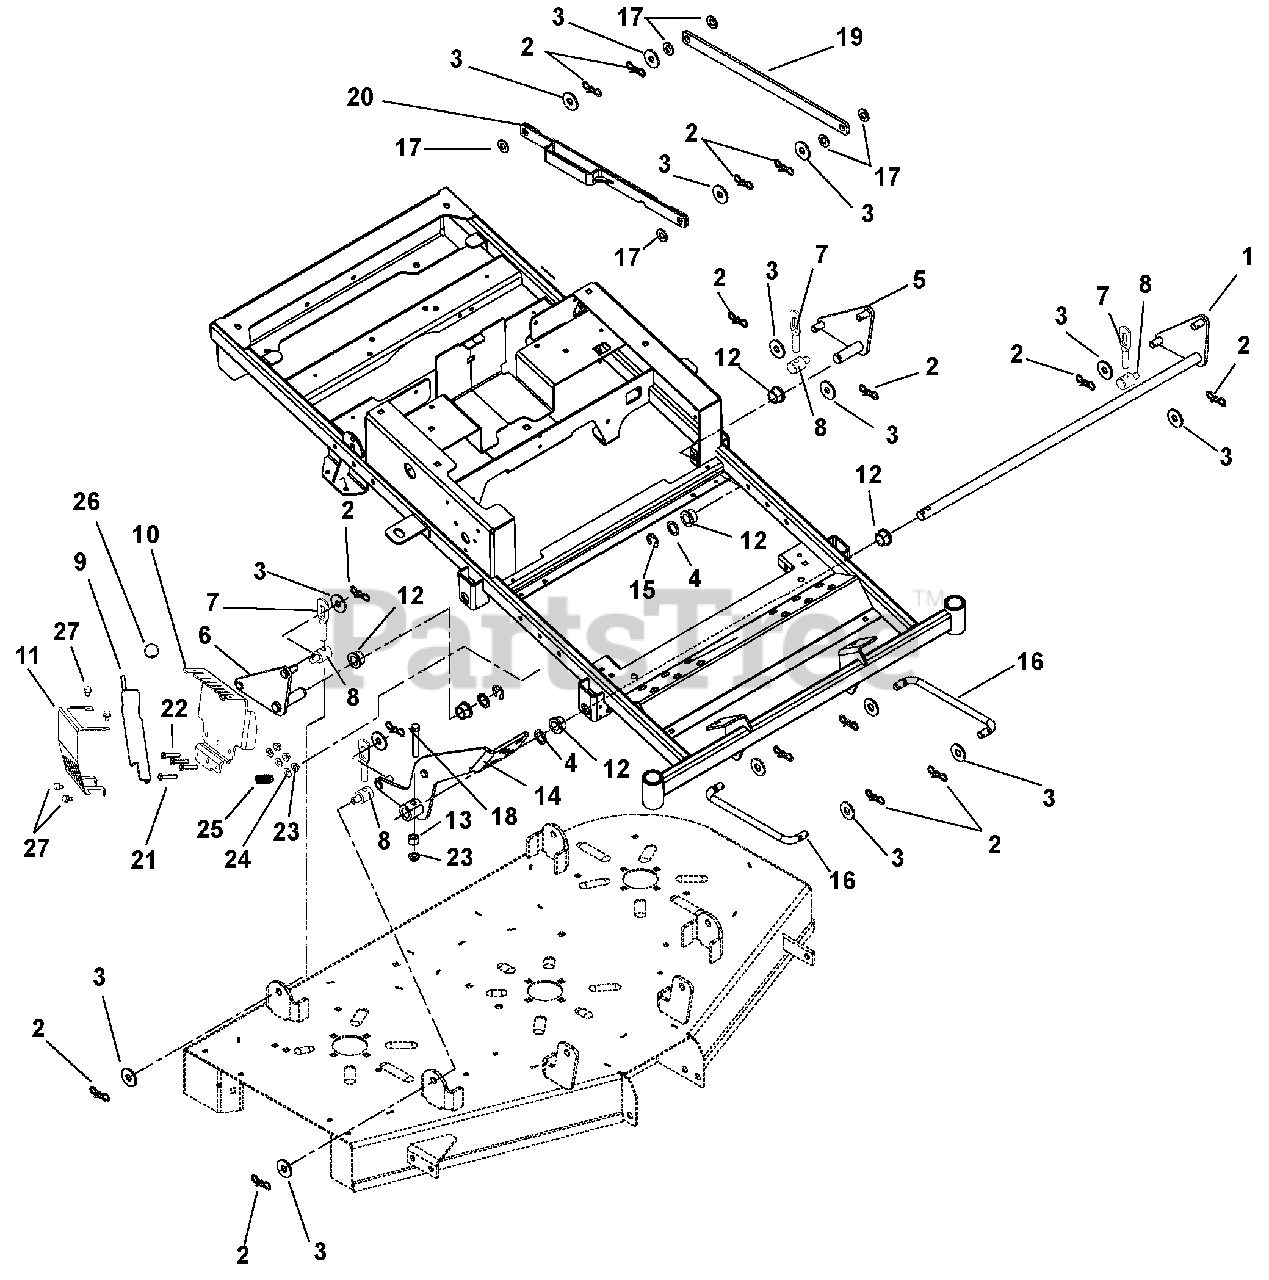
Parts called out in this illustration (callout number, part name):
1	WMT-DECK PIVOT FRONT
2	PIN,BOW TIE LOCKING .091X1.875
3	WSHR-FL-STL.511X1.441X.125 YWZ
4	WSHR-FL-STL.754X1.125X.062YWZC
5	WMT-DECK PIVOT ZTXL REAR LH
6	WMT-DECK PIVOT ZTXL REAR RH
7	DECK LINK
8	TRUNNION-.50
9	LEVER, HOC WLDMT XL
10	BRACKET, ADJUSTER HOC XL
11	GUARD, PLATE FIXED
12	BSHG-FLG .750X1.000X.625X1.250
13	BSHG-SLV .391X.688X.52 PM
14	WMT-ZTXL FOOT PEDAL
15	RG-RTNG-EXT .750X.050
16	LINK, DRAG
17	WSHR-FL-NYL .518X1.000X.080
18	@BLT-HEX .38-16X2.50 GR5 YWZC
19	LINK, LIFT
20	HOC, LINK RETAINING XL
21	@BLT-HEX .38-16X2.25 GR5 YWZC
22	@BLT-HEX .38-16X1.75 GR5 YWZC
23	@NUT-LK-NYL-FLG .38-16 YWZC
24	@WSHR-FL-STL.38X.875X.083 YWZC
25	SPRING, COMPRESSION
26	KNOB,BALL -BLACK 1.47" .375-16
27	SCR-TAP .25-20X.50 HWH TR YWZ
